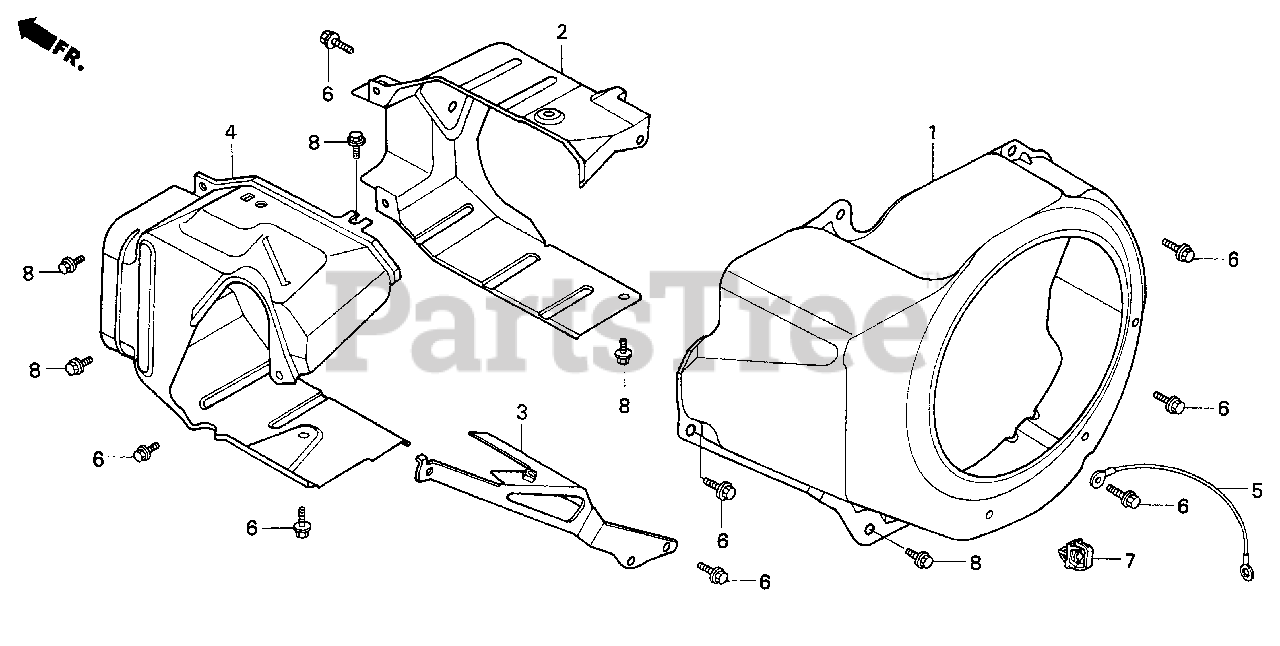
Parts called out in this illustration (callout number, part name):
1	COVER, FAN
2	SHROUD, CYLINDER
3	STAY, SHROUD
4	SHROUD, HEAD
5	CABLE ASSY., BONDING
6	BOLT, FLANGE (6X12) (CT200)
7	CLIP, WIRE HARNESS (BLACK)
8	BOLT, FLANGE (6X8)
